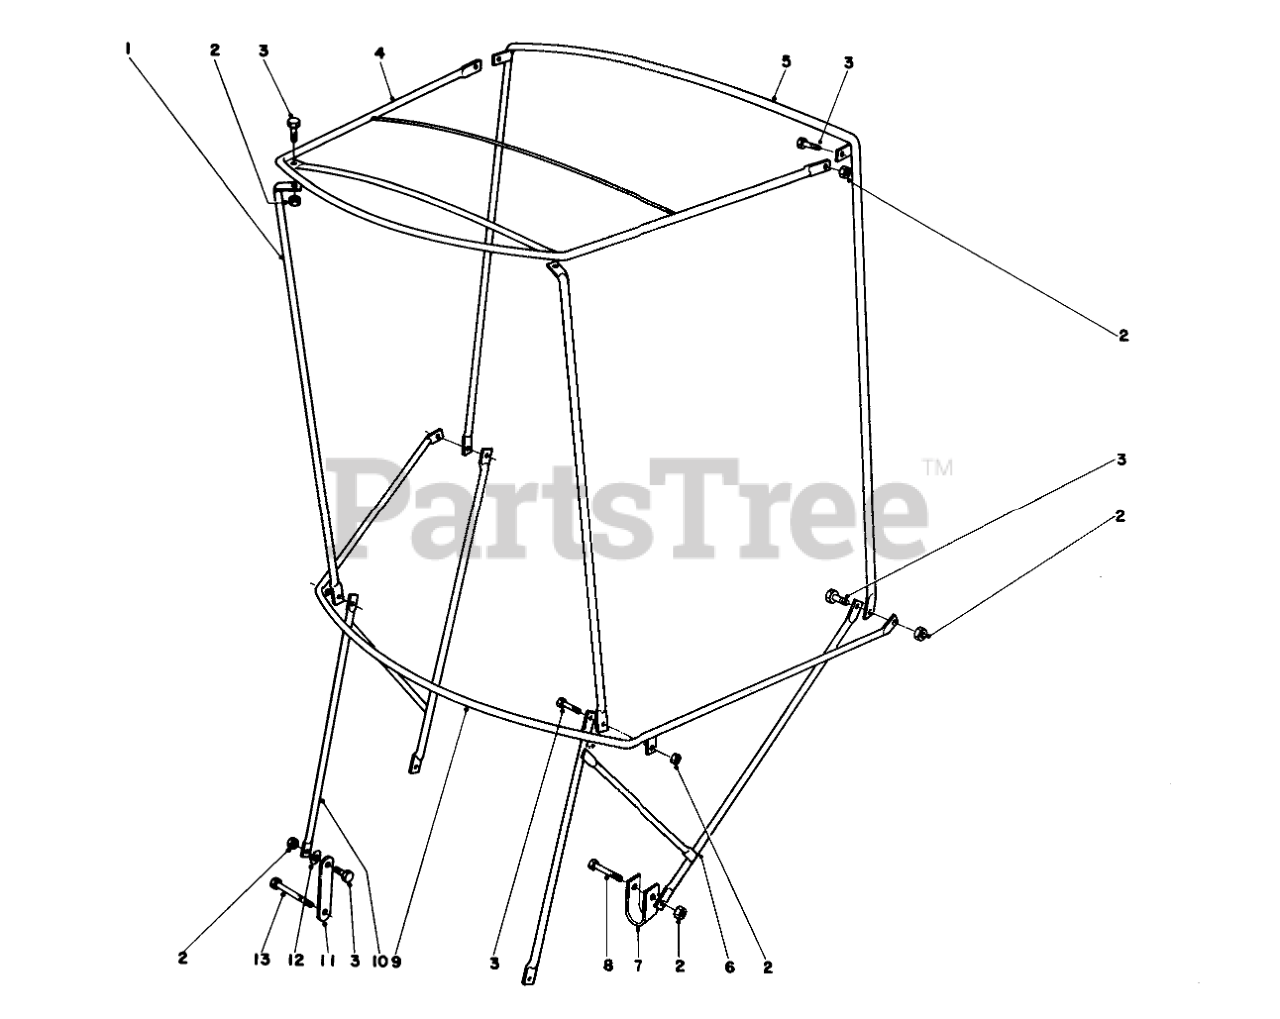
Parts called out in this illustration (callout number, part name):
2	NUT-LOCK
3	SCREW-HH
4	FRAME-TOP
5	BOW-VERTICAL, REAR
6	Attaching Bracket, L.H.
7	U CLAMP
8	SCREW-HH
9	BOW-CURVED
10	Attaching Bracket, R.H.
11	Mounting Strap
12	WASHER-LOCK/EXT
13	SCREW-HH
